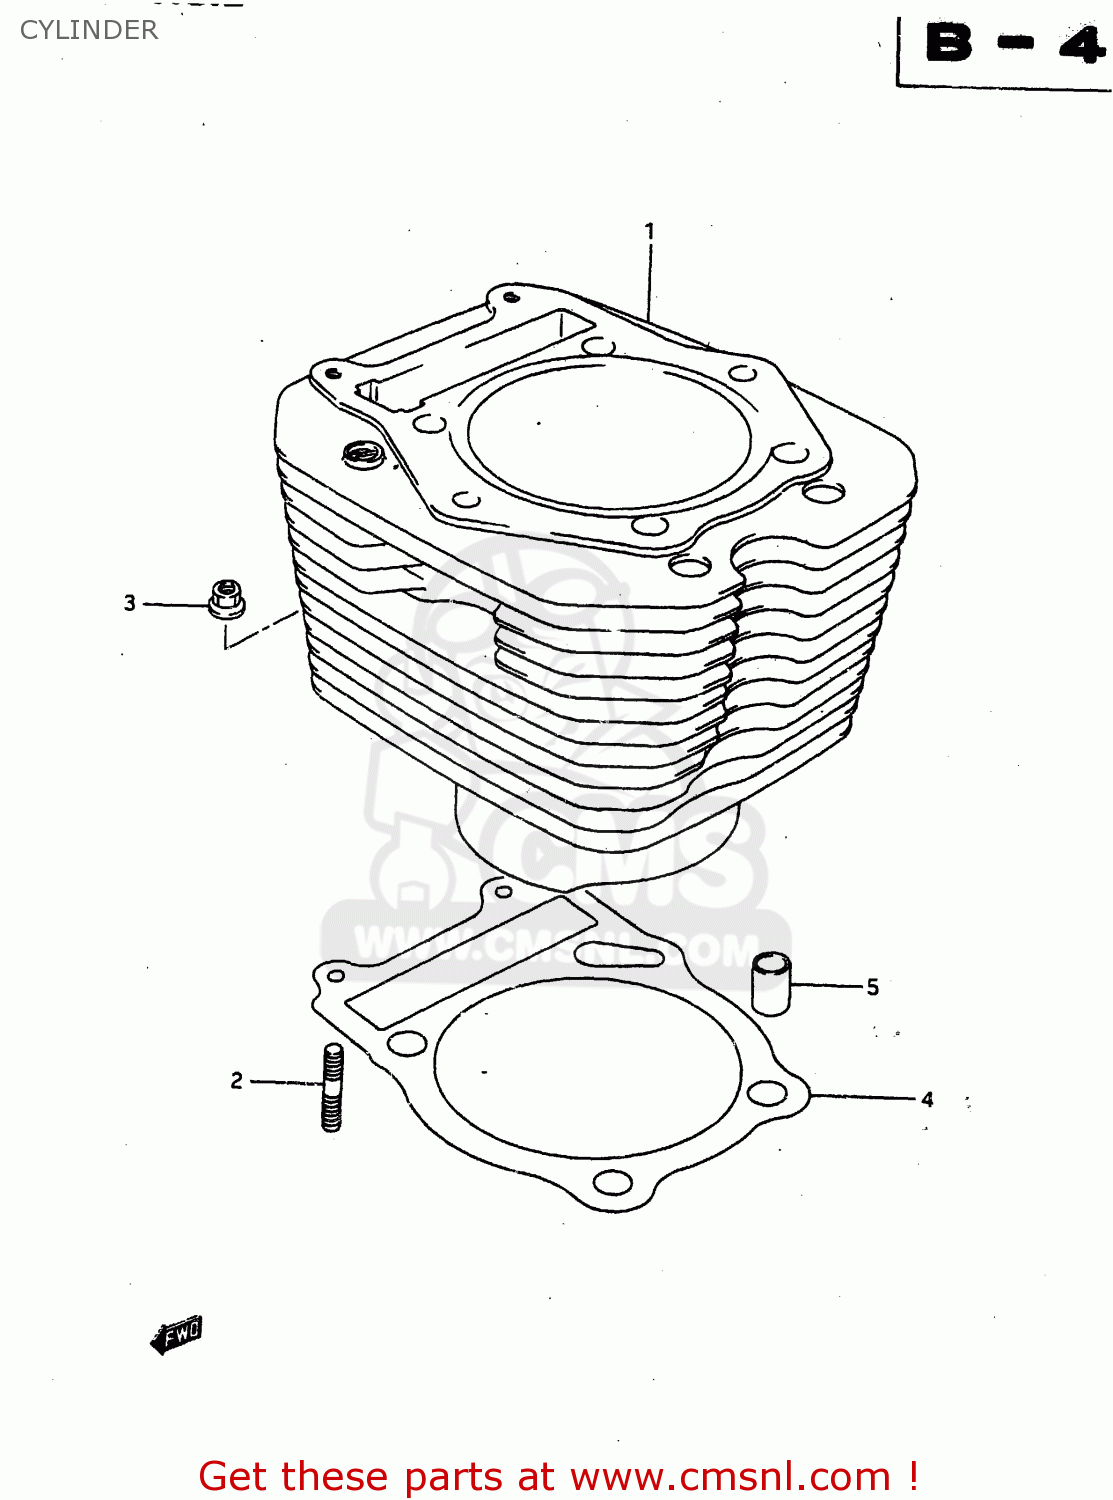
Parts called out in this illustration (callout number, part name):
1	CYLINDER
2	STUD BOLT L:20
3	NUT 6MM
4	GASKET,CYLINDER (NAS)
5	PIN
